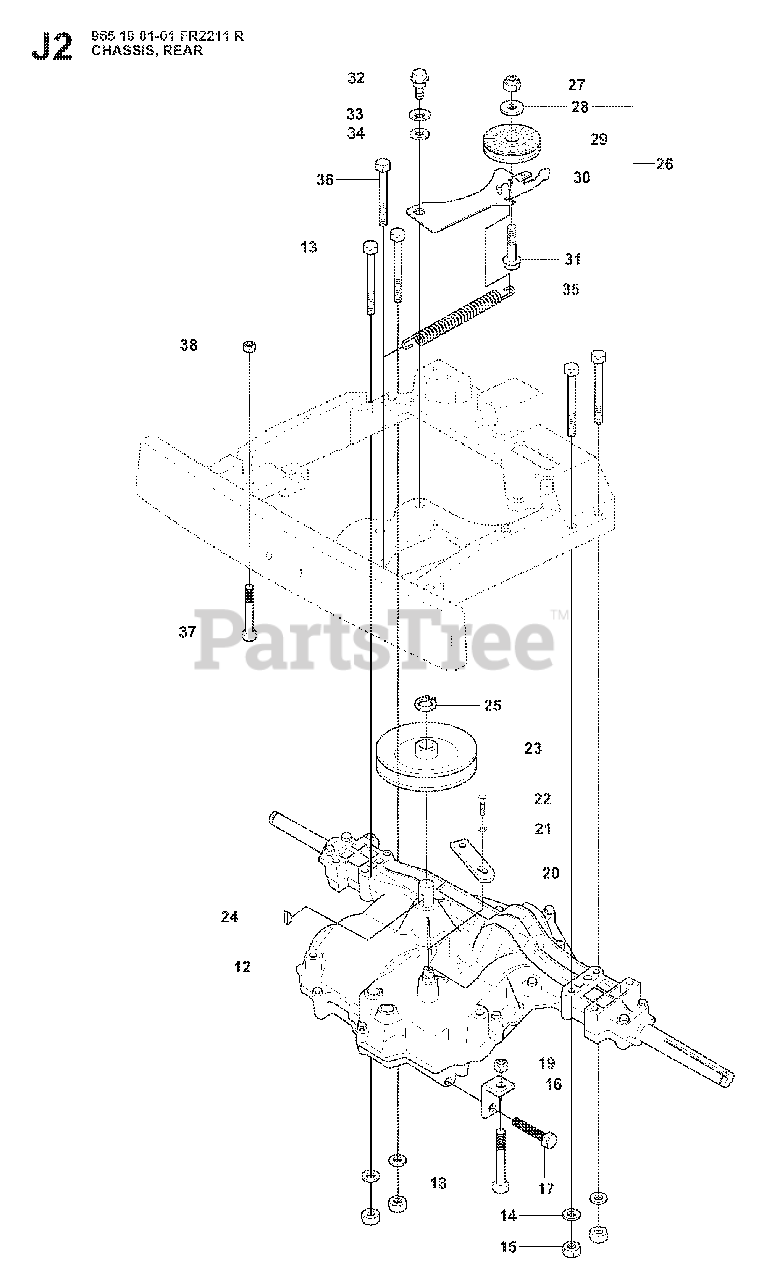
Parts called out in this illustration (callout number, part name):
14	WASHER BRB 8.4X17
15	NUT
16	WIRE BRACKET
19	NUT
21	WASHER
25	RETAINING RING SGA 16
27	LOCKNUT M8
33	SPRINGWASHER
34	WASHER - M12
38	NUT
